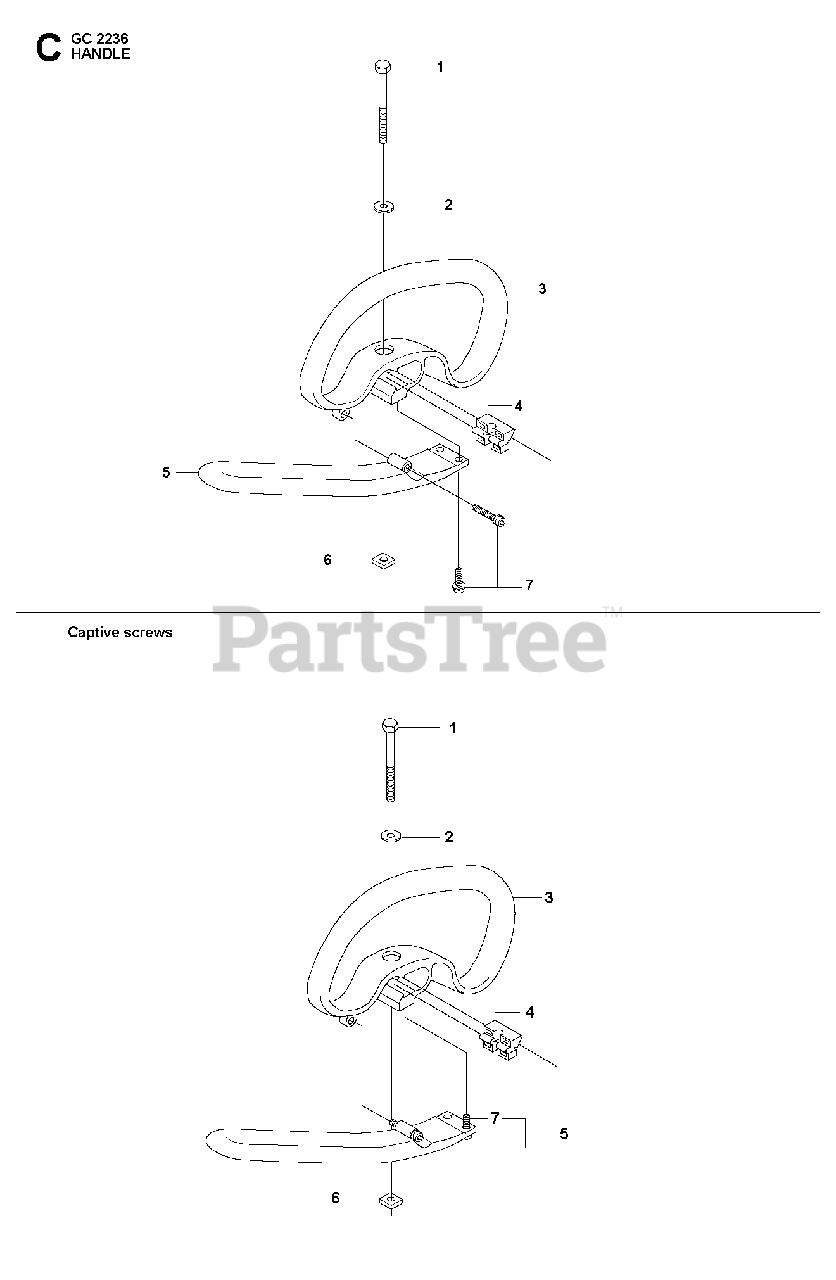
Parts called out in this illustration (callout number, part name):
3	HANDLE.LOOP
4	SPACING BLOCK
5	HANDLE
7	SCREW
7	SCREW IHSCFTO
